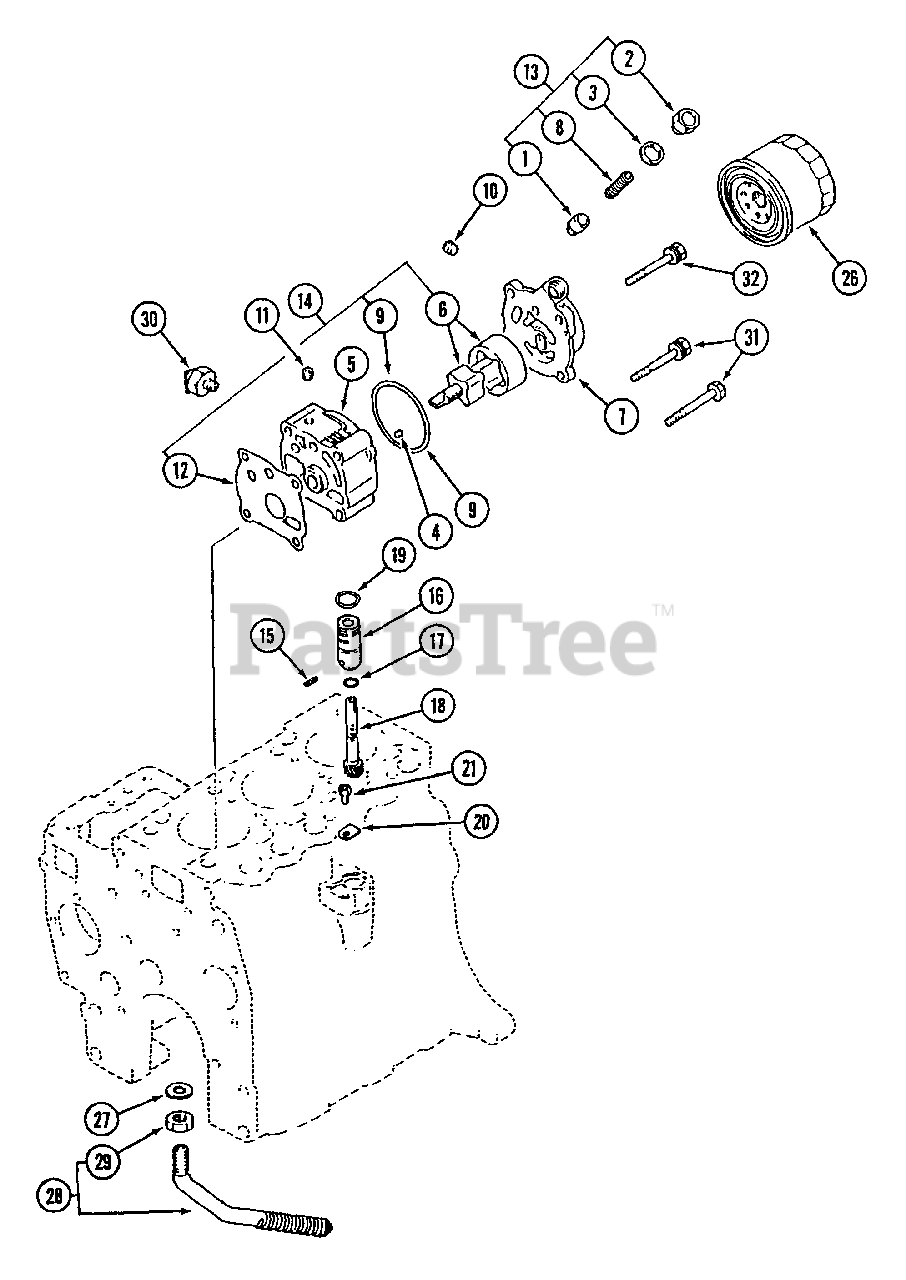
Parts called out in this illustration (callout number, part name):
1	Plunger, Relief
3	Gasket, Oil Drain Plug
4	Pin, Dowel
5	Body, Oil Pump
6	Rotor Ass'y., Oil Pump
7	Cover, Oil Pump
8	Spring, Relief
12	Gasket, Oil Pump Body
13	Service Kit, Relief Valve
14	Service Kit, Rotor
15	Pin, Spring
16	Sleeve, Speedometer Gear
18	Gear, Speedometer Driven
19	O-Ring
20	Plate, Locking
21	Bolt, w/Washer
26	Filter Ass'y., Oil
28	Screen Ass'y., Oil
30	Switch Ass'y., Oil Pressure
31	Bolt, Washer Ass'y.
32	Bolt, Washer Ass'y.
